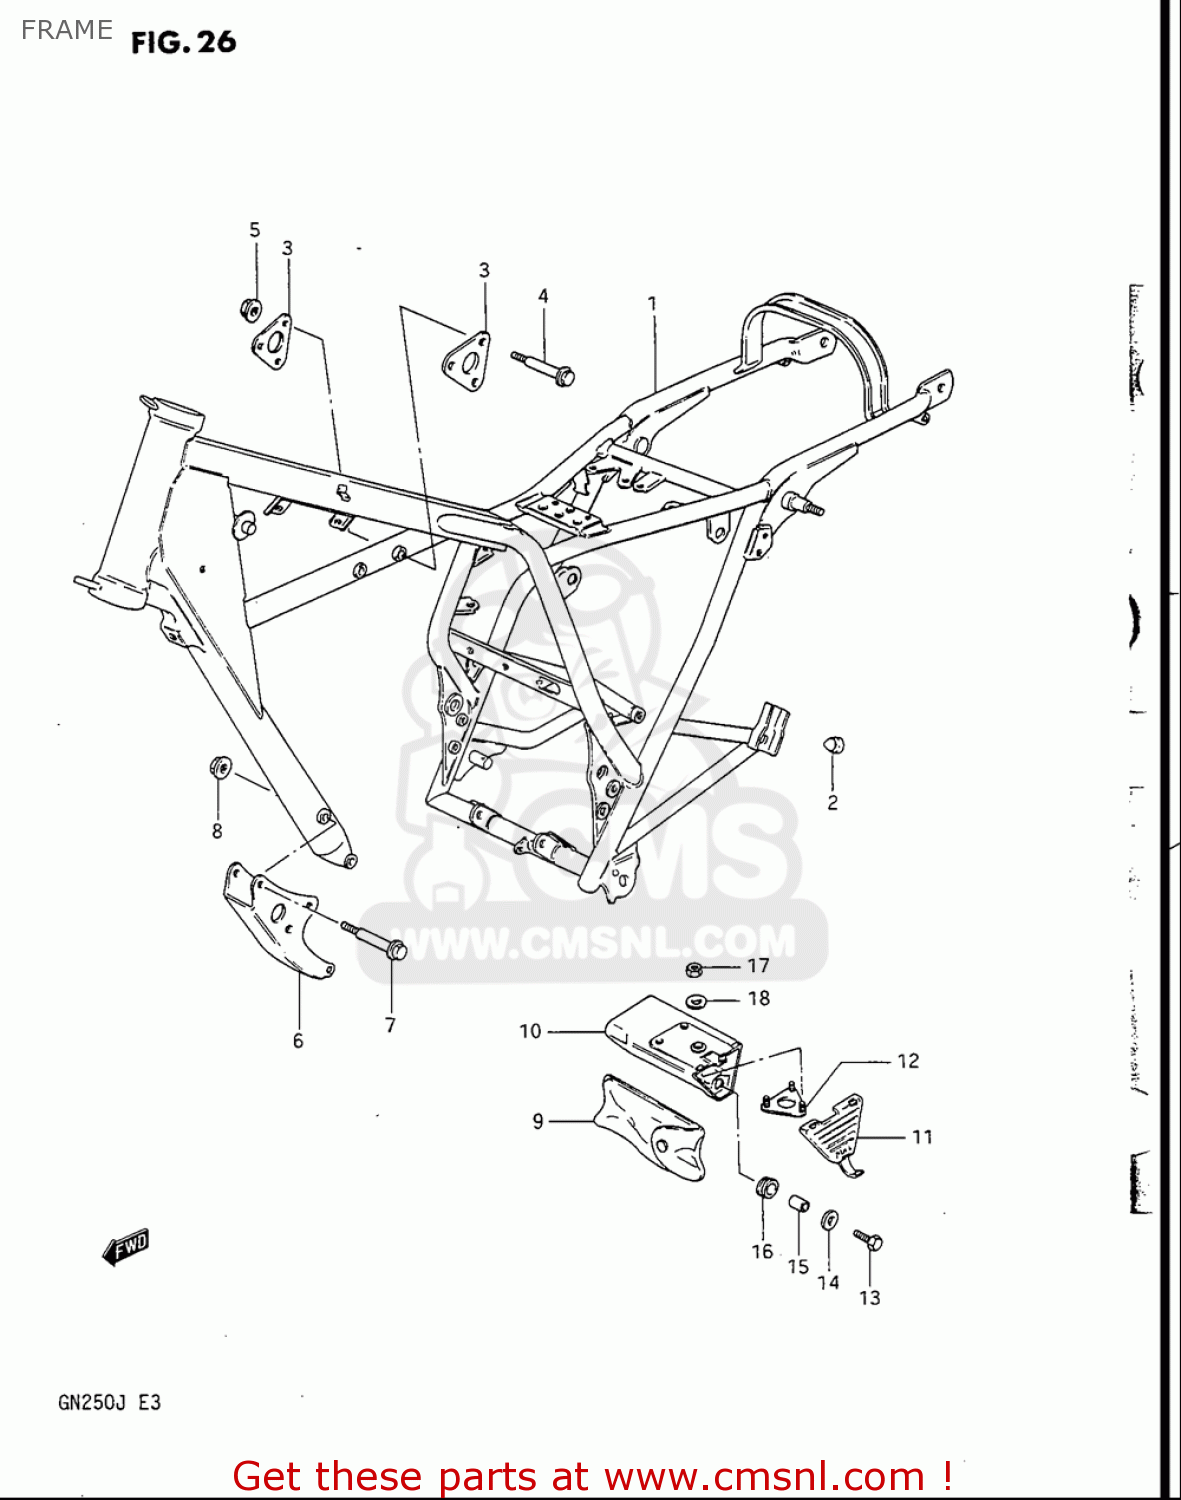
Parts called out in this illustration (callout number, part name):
1	FRAME
2	PLUG(OD:19)
3	PLATE,ENGINE MOUNT UPR
4	BOLT
5	NUT
6	PLATE,ENGINE MOUNT LWR
7	BOLT
8	NUT
9	TOOL ASSY
10	BOX,TOOL
11	CAP,TOOL BOX
12	PLATE,TOOL HOLDER
13	BOLT
14	WASHER(6.5X20X1.2)
15	SPACER(6.1X9X7.5)
16	CUSHION
17	NUT
18	WASHER
